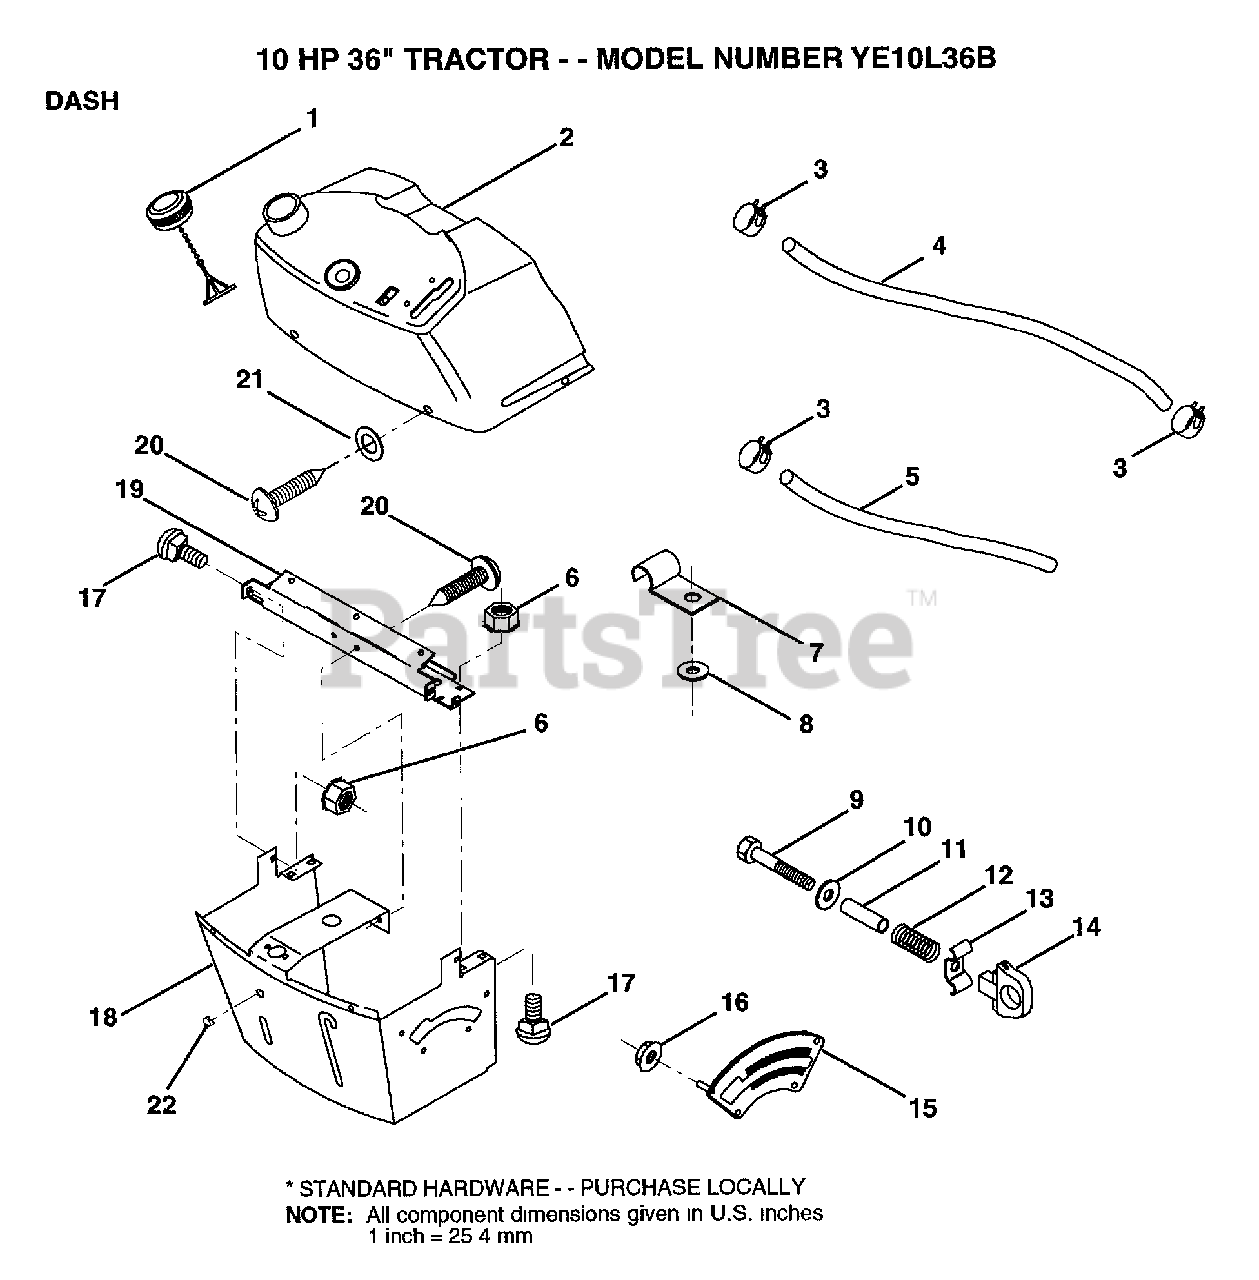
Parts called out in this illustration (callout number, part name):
3	HOSE CLAMP
5	FUEL LINE T
6	NUT
7	CLIP T
8	WASHER PM
9	BOLT
11	SPACER SPLIT
12	SPRING M
13	"KNOB,HGT RETAINER"
14	KNOB
15	ADJUSTER QUAD
16	NUT
17	BOLT
18	SUPT ASSY DASH
19	CROSS BRACE
22	PLUG DOME
